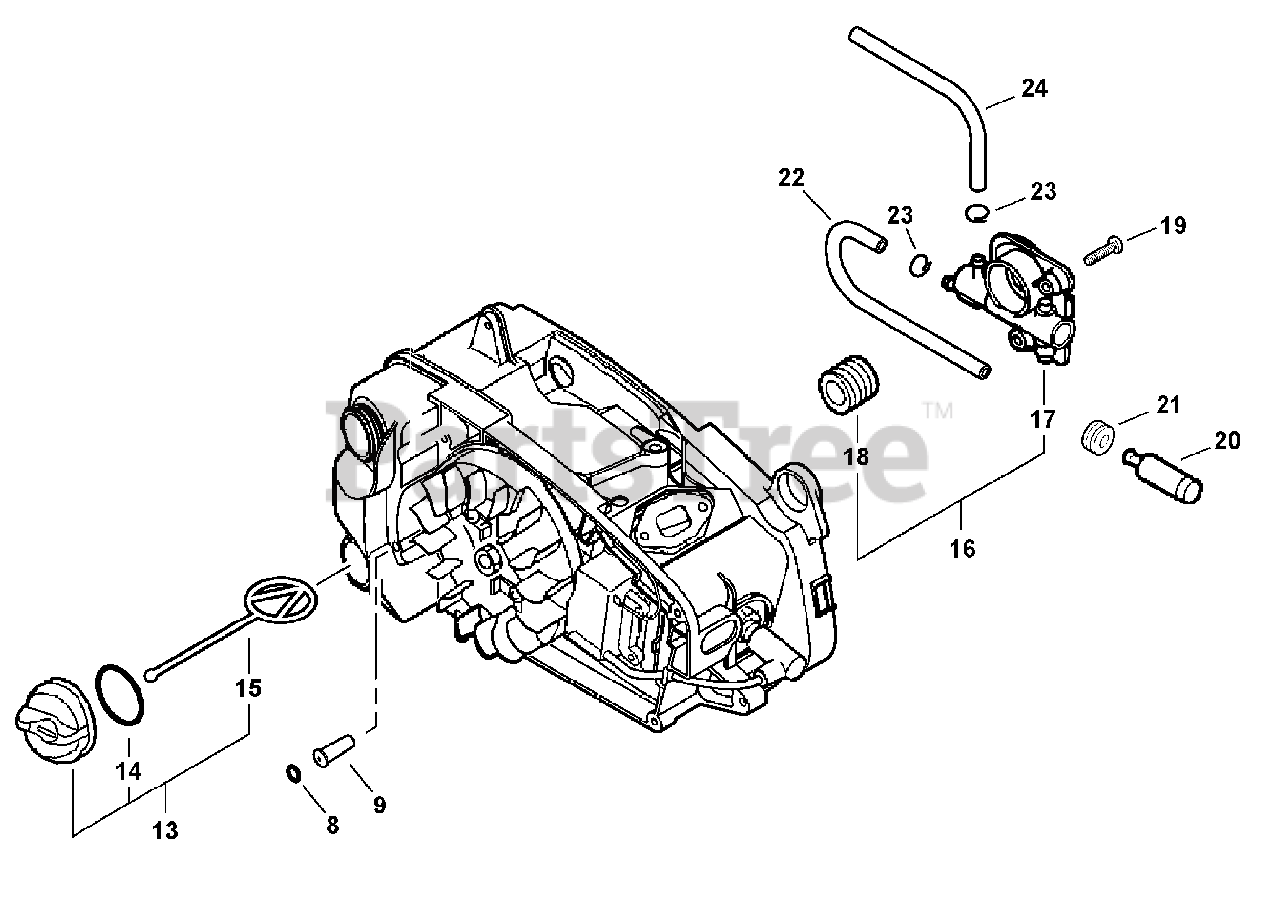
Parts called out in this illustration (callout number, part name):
8	O-RING S-4
9	VENT ASSY
13	CAP ASSY - BLACK
14	O-RING 18
15	CONNECTOR, CAP L= 60 MM
16	AUTO-OILER KIT
17	AUTO-OILER ASSY
18	GEAR, WORM
19	SCREW 4×12
20	FILTER, OIL
21	GROMMET
22	PIPE 3×6×185 MM BLACK
23	CLIP Ø6.5 MM
24	PIPE 3×6×90 MM
